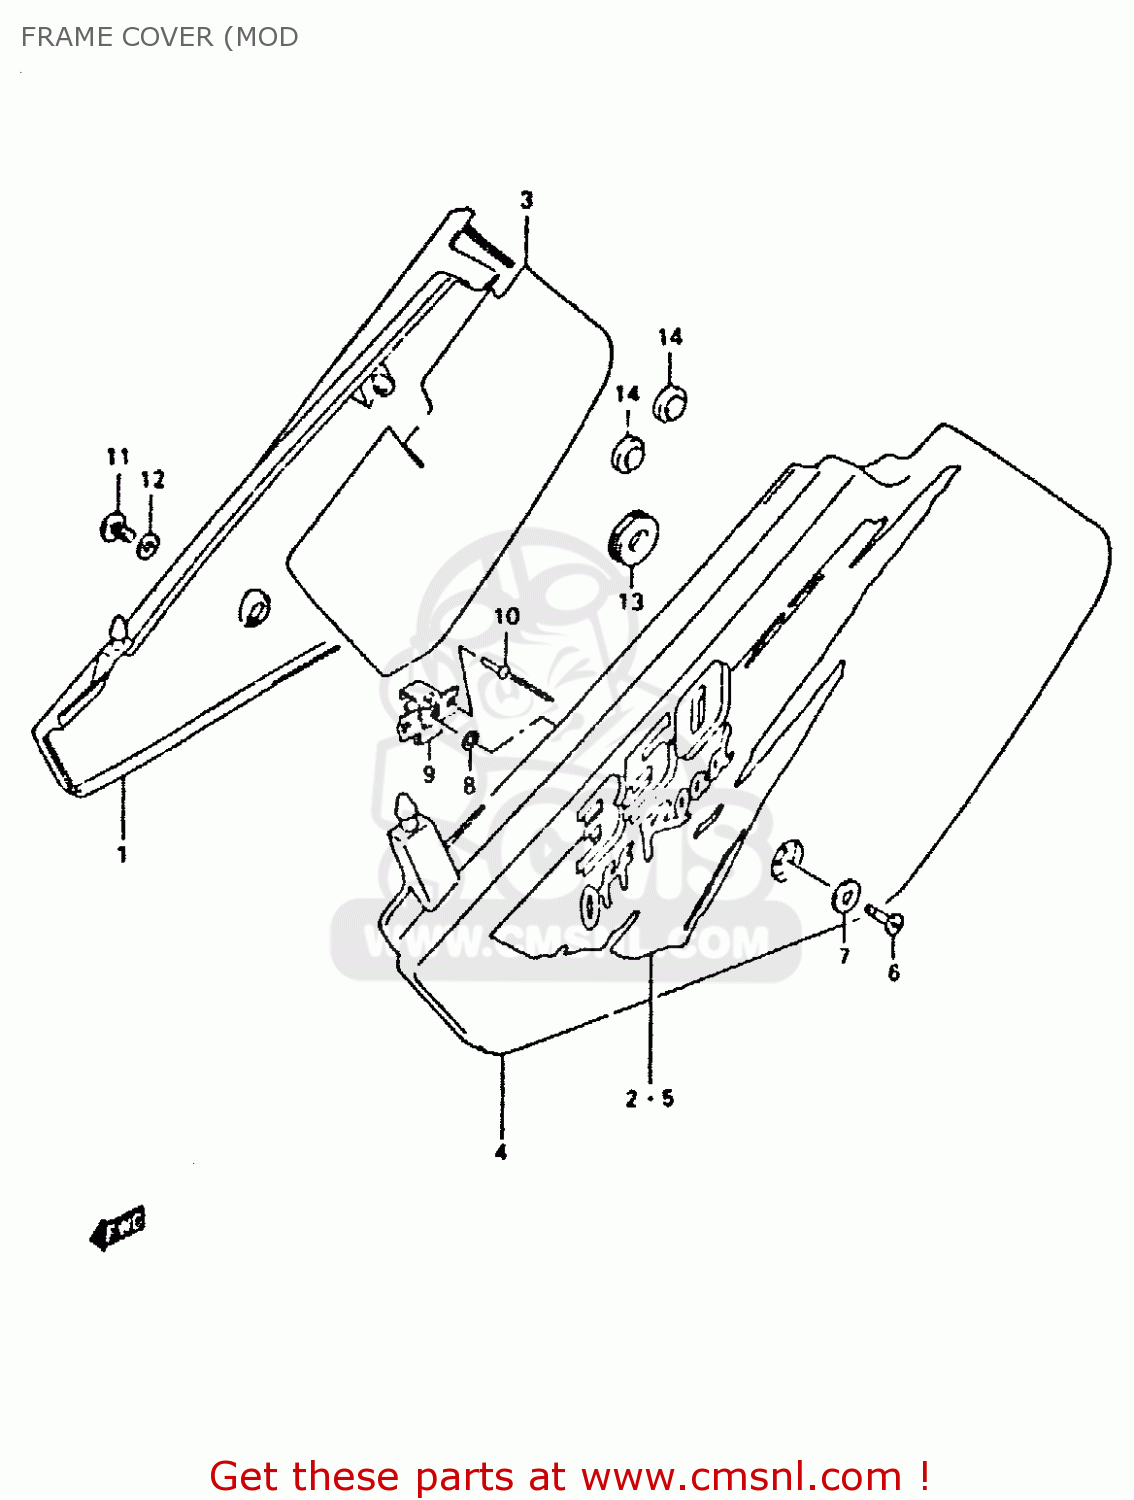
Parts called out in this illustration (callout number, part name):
1	COVER,FRAME,R(WHITE)
2	TAPE,FRAME COVER,R
3	SHIELD,FRAME COVER,R
4	COVER,FRAME,L(WHITE)
5	TAPE,FRAME COVER,LEFT
6	STUD,FRAME COVER,LEFT
7	WASHER
8	RETAINER,FRAME COVER STUD,L
9	PLATE,FITING
10	RIVET
11	SCREW
12	RIVET
13	SCREW
14	WASHER
15	CUSHION
16	CUSHION
